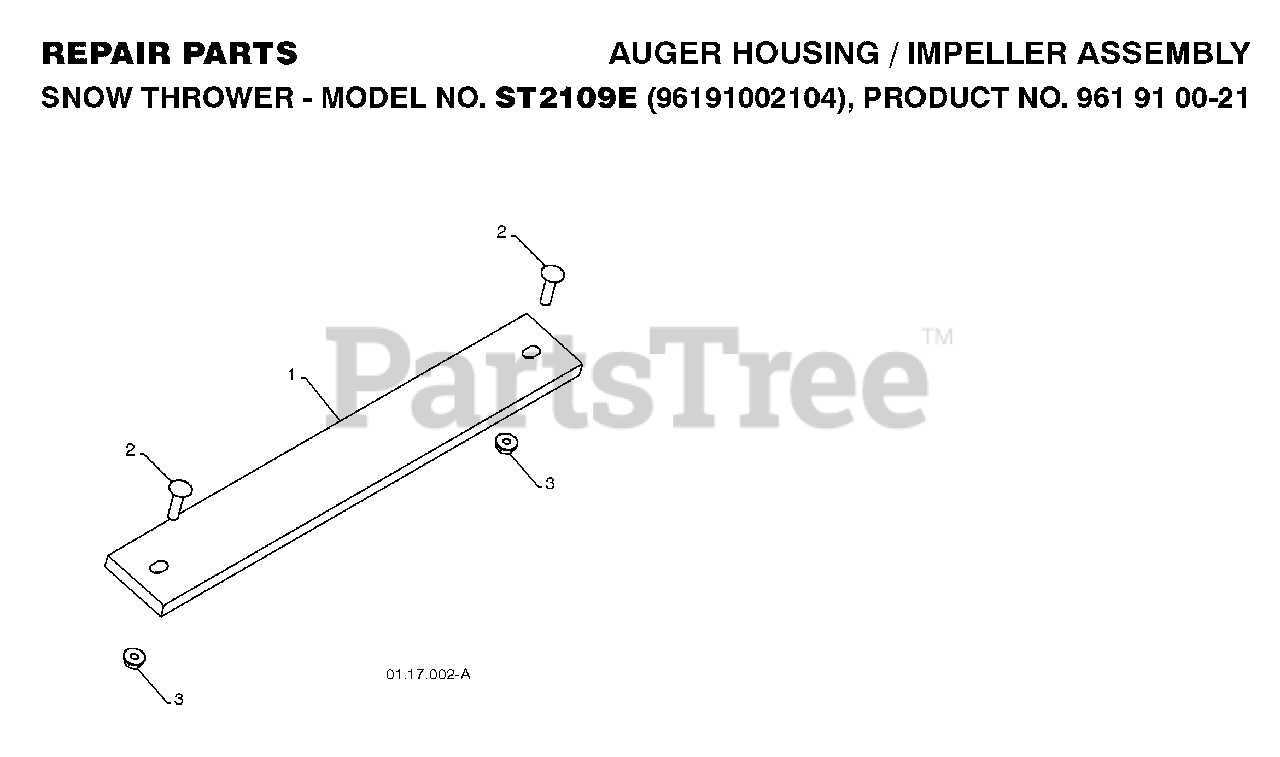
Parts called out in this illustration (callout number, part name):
1	WEIGHT, AUGER HOUSING 27
2	BOLT.CARRIAGE.5/16-18
3	NUT, LOCK 5/16-18
